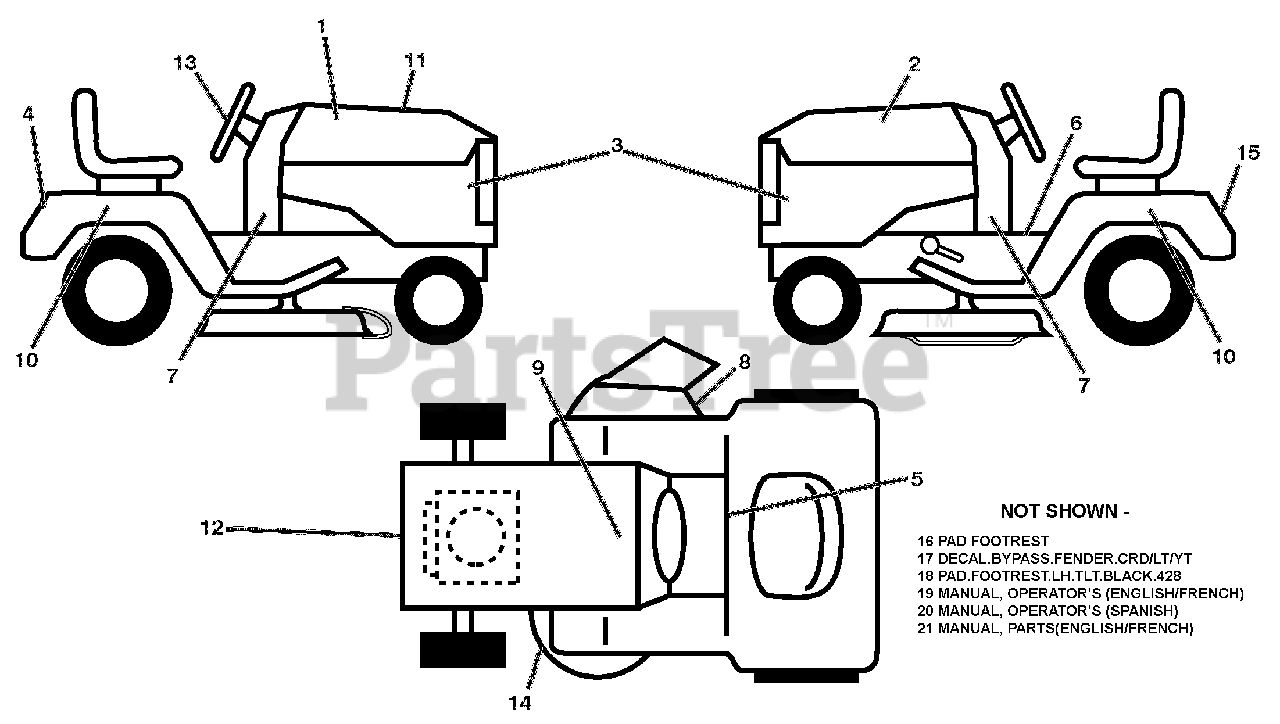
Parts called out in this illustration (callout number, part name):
1	DECAL.HOOD.RH.PRECISION.ARIENS
2	DECAL.HOOD.LH.PRECISION.ARIENS
3	DECAL.SDPNL.PWRDBY KOHL.ARIENS
4	Decal, Fender
5	Decal, Flag
6	DECAL, WARNING START INST.
7	DECAL.DASH.LWOWER.20HP.ARIENS
8	DECAL.MOWER.WARN.KEEP HAND AWY
9	DECAL.BAT.DAN/POI P/L SYM.WPN
10	DECAL.FENDER.SIDE.HYDRO.ARIENS
11	DECAL, REPLACEMENT
12	DECAL ENGINE
13	DECAL.WHEEL.STEER.ARIENS
14	DECAL.V-BELT.SCH.42/46"MEC/ELE
15	Decal Fender Service
